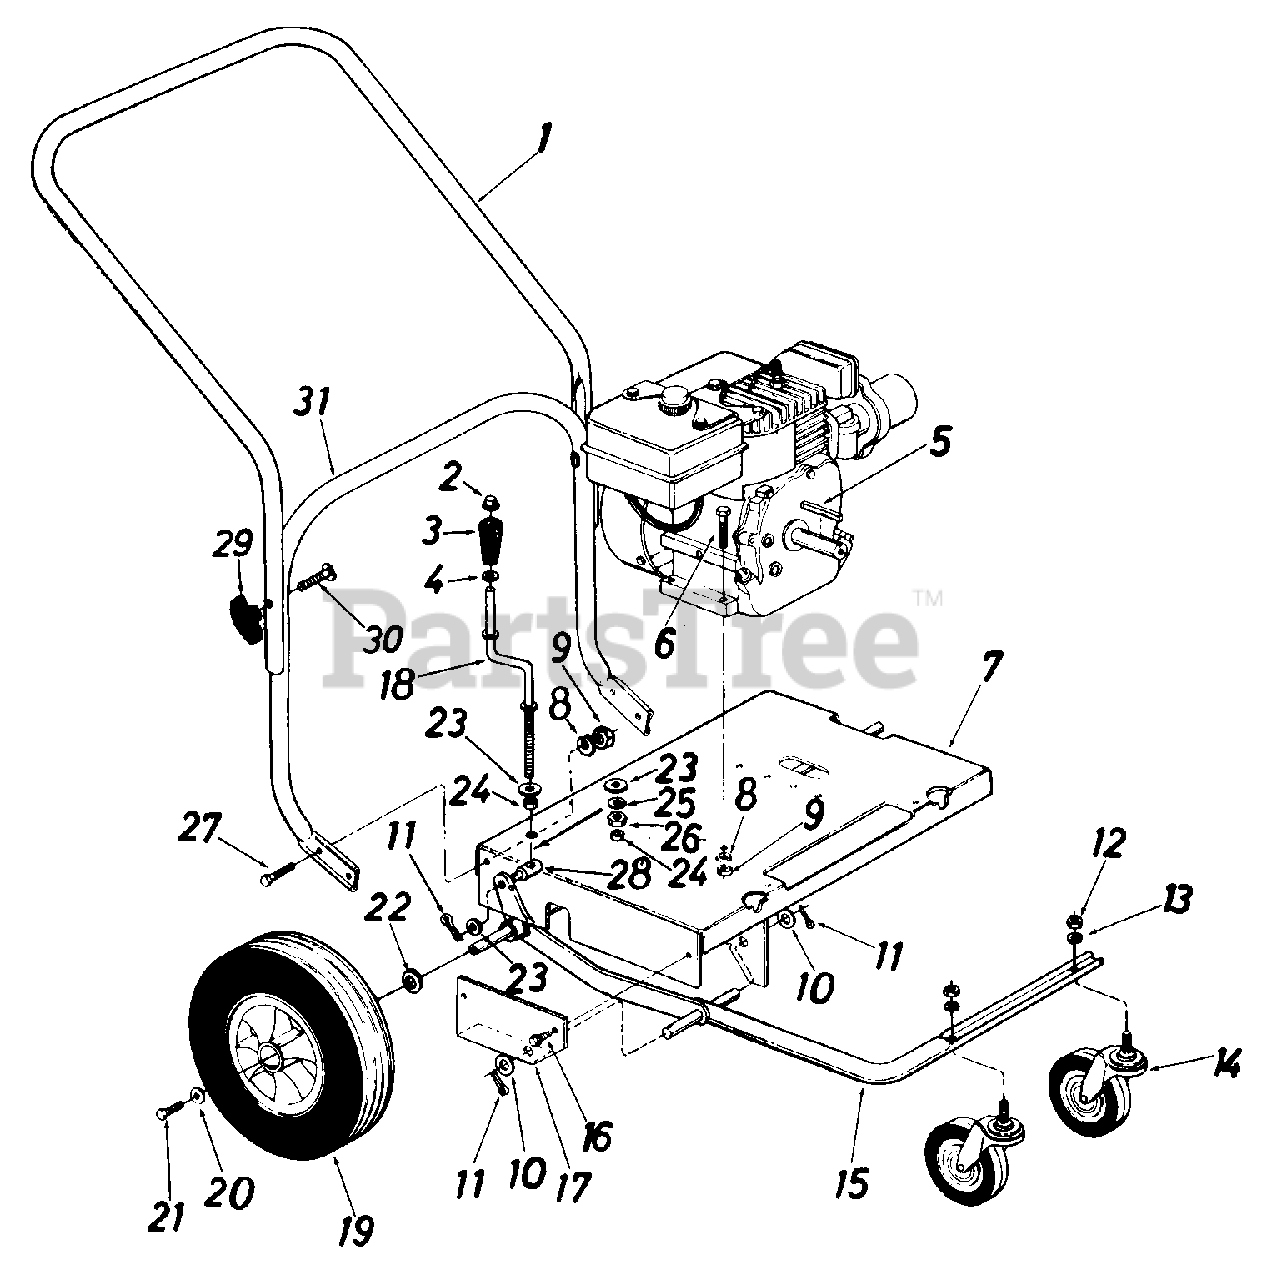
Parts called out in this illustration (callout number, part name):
2	Push Nut 3/8" Rod
3	Crank Knob
4	Fl.-Wash. .385" I.D. x .62" O.D.
5	Sq. Key 1/4" x 2.0" Lg.*
6	Hex Bolt 5/16-18 x 1.50" Lg.*
9	Hex Nut 5/16-18 Thd.*
10	Fl.-Wash. .63" I.D. x 1.25" O.D.
11	Cotter Pin 1/8" Dia. x 1.0" Lg.
12	Hex Nut 1/2-13 Thd.*
13	L.-Wash. 1/2" I.D.*
14	Swivel Caster Wheel 5" Dia. x 1.25"
19	Wheel Ass'y. Comp. 12" x 3" (Plastic)
20	Fl.-Wash. 34" I.D. x .87" O.D.
21	Hex Locking Bolt 5/16-24 x .64" Lg.
22	Fl.-Wash.
23	Fl.-Wash. .38" I.D. x .57" O.D.
24	Spacer.382" I.D. x .50" x .180" Lg.
25	L.-Wash. 3/8" I.D.
26	Hex Nut 3/8-8 Thd.
27	Hex Bolt 5/16-18 x .75" Lg.
28	Ferrule
29	Hand Knob
30	Carriage Bolt 5/16-18 x 2.0" Lg.
